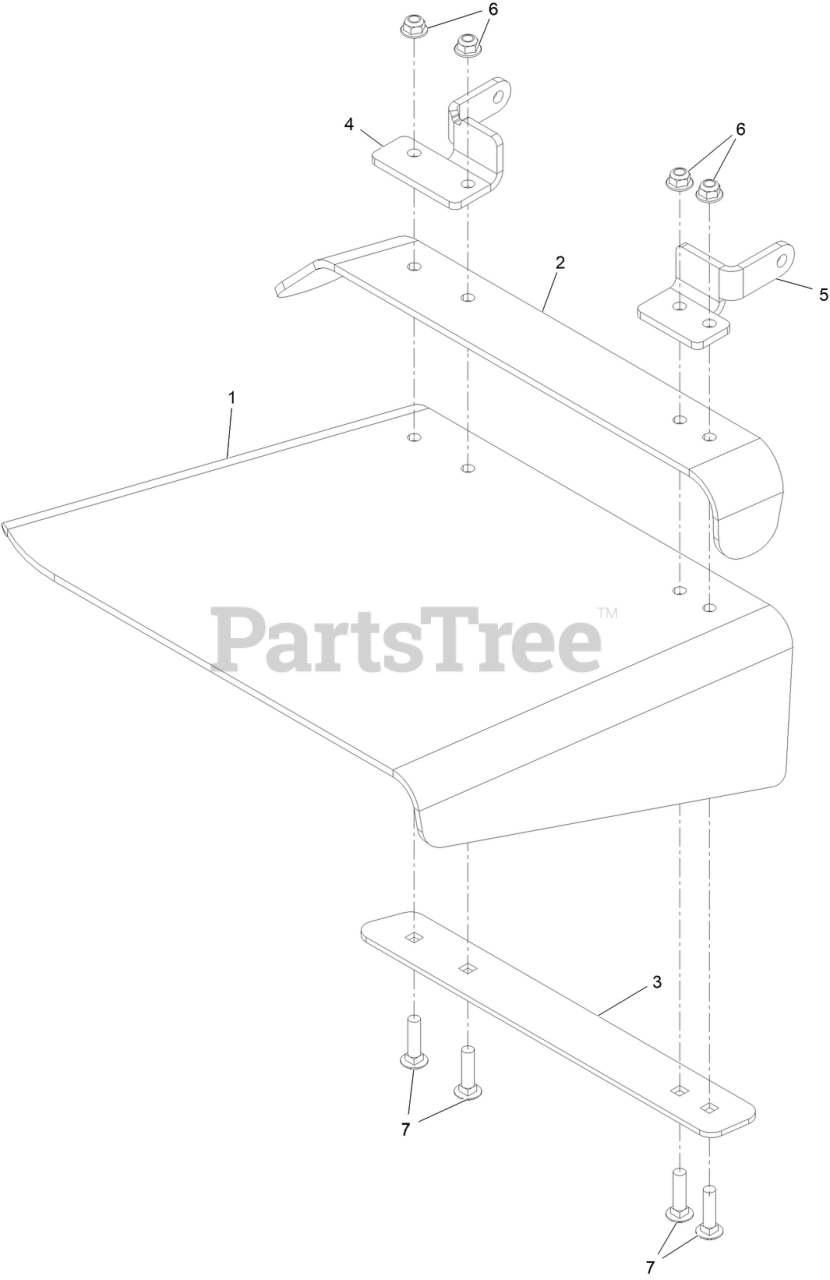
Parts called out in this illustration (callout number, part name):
1	DEFLECTOR-DECK, RUBBER
2	DEFLECTOR
3	STRAP-DISCHARGE
4	PLATE- HINGE, REAR
5	PLATE-HINGE, FRONT
6	NUT-HF, NI
7	SCREW-CARR
